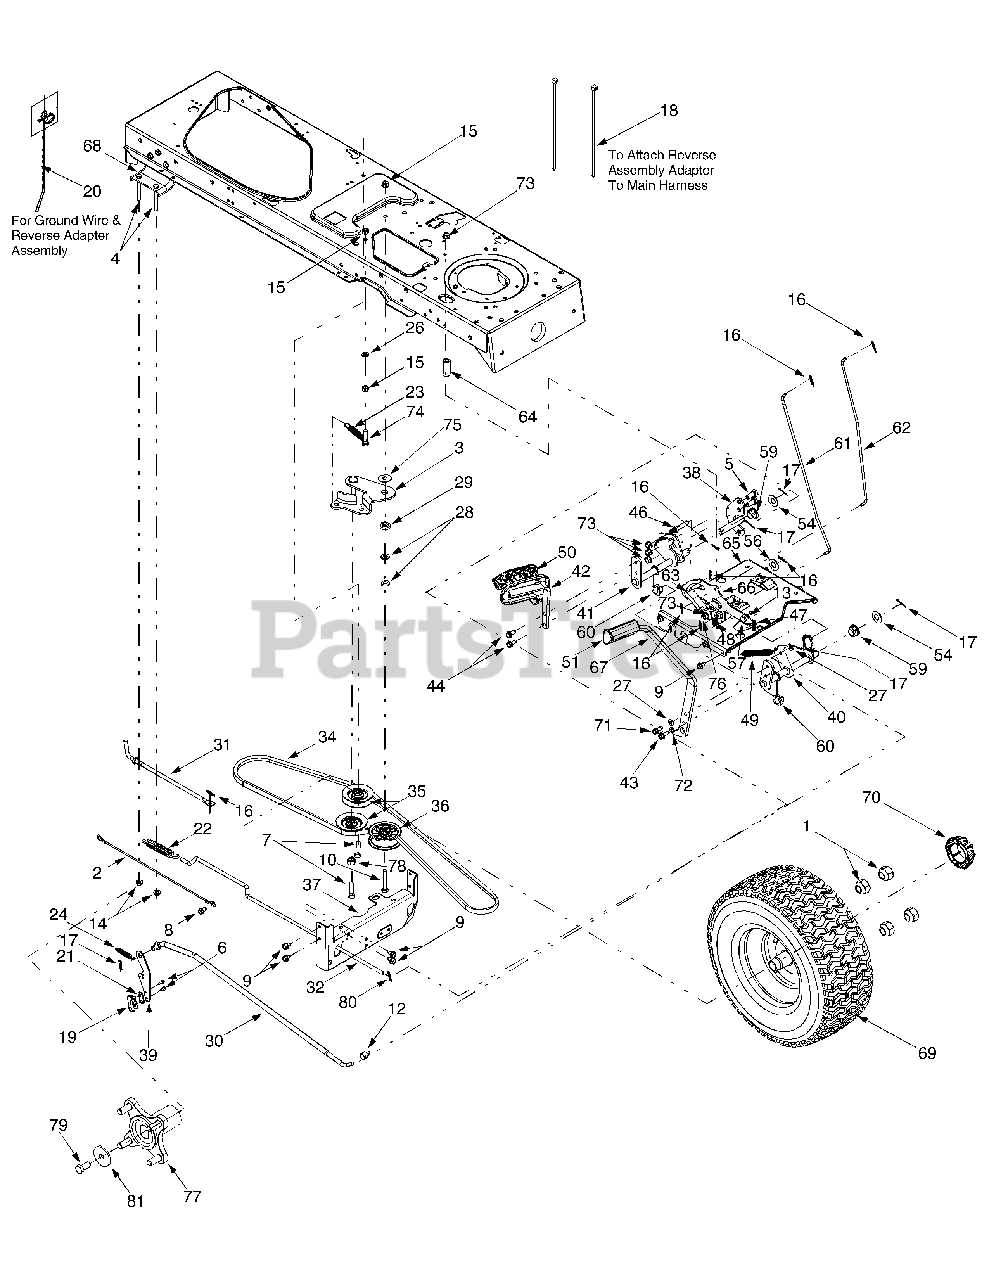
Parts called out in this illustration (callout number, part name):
1	Lug Nut, 3/4-16
2	Reverse/Ground Wire Harness Adapter
4	Hex Cap Screw, 5/16-18 x 2.75
5	Hex Cap Screw, 3/8-16 x.75
6	Screw, #8-18 x.5
7	Hex Cap Screw, 3/8-16 x 1.5
8	Self-tapping Screw, 1/4-20 x.50
9	Self-tapping Screw, 5/16-12 x.75
10	Hex Cap Screw, 3/8-16 x 2.25
12	Ferrule, 3/8-24
13	Flange Lock Nut, 5/16-18
14	Flange Lock Nut, 5/16-18
15	Hex Nut, 3/8-16
16	Internal Cotter Pin
19	Short Spring Switch
20	Push-mount Cable Tie
21	Insulator Nut Plate
22	Extension Spring,.59 x 4.0
23	Extension Spring,.770 x 3.72 Lg.
24	Extension Spring, 3/8 x 1.44
26	Lock Washer, 3/8
27	Flat Washer,.344 x.750 x.120
28	Flat Washer,.407 x.812 x.135
29	Shoulder Spacer,.38
30	Hydrostatic Control Rod
31	Hydrostatic Bypass Rod
32	Hydrostatic Brake Rod
34	Drive Belt
35	V-idler Pulley, 3.06
36	Flat Idler Pulley, 2.75
43	Self-tapping Screw, 5/16-18 x.875
44	Self-tapping Screw, 5/16-18 x.75
46	Pin, 3/8-16 x 2.43
47	Compression Spring,.40 OD x 1.17
48	Extension Spring,.50 OD x 1.41
49	Extension Spring,.50 OD x 6.37
50	Drive Pedal Pad
51	Brake Pedal Pad
54	Flat Washer,.64 x 1.24 x.06
56	Flat Washer,.385 x.870 x.092
57	Shoulder Screw,.437 x 1.62
59	Hex Flange Bearing
60	Split Hex Flange Bearing
61	Cruise Control Rod
62	Brake Lock Control Rod
63	Cruise Latch
64	Spacer, 5/16 x 1.54
66	Drive Lockout Bracket
70	Hub Cap
71	Self-tapping Screw, 5/16-18 x.75
72	Lock Washer, 5/16
73	Flange Lock Nut 3/8-16
74	Hex Cap Screw, 3/8-16 x 1.5
75	Flat Washer.385 x 1.00 x.135
76	Shoulder Screw 3/8-16.50 x.27
77	Wheel Hub Assembly
78	Jam Nut, 7/16-20
79	Screw, 3/8-16 x.750
81	Flat Washer,.390 x 1.500 x.134
